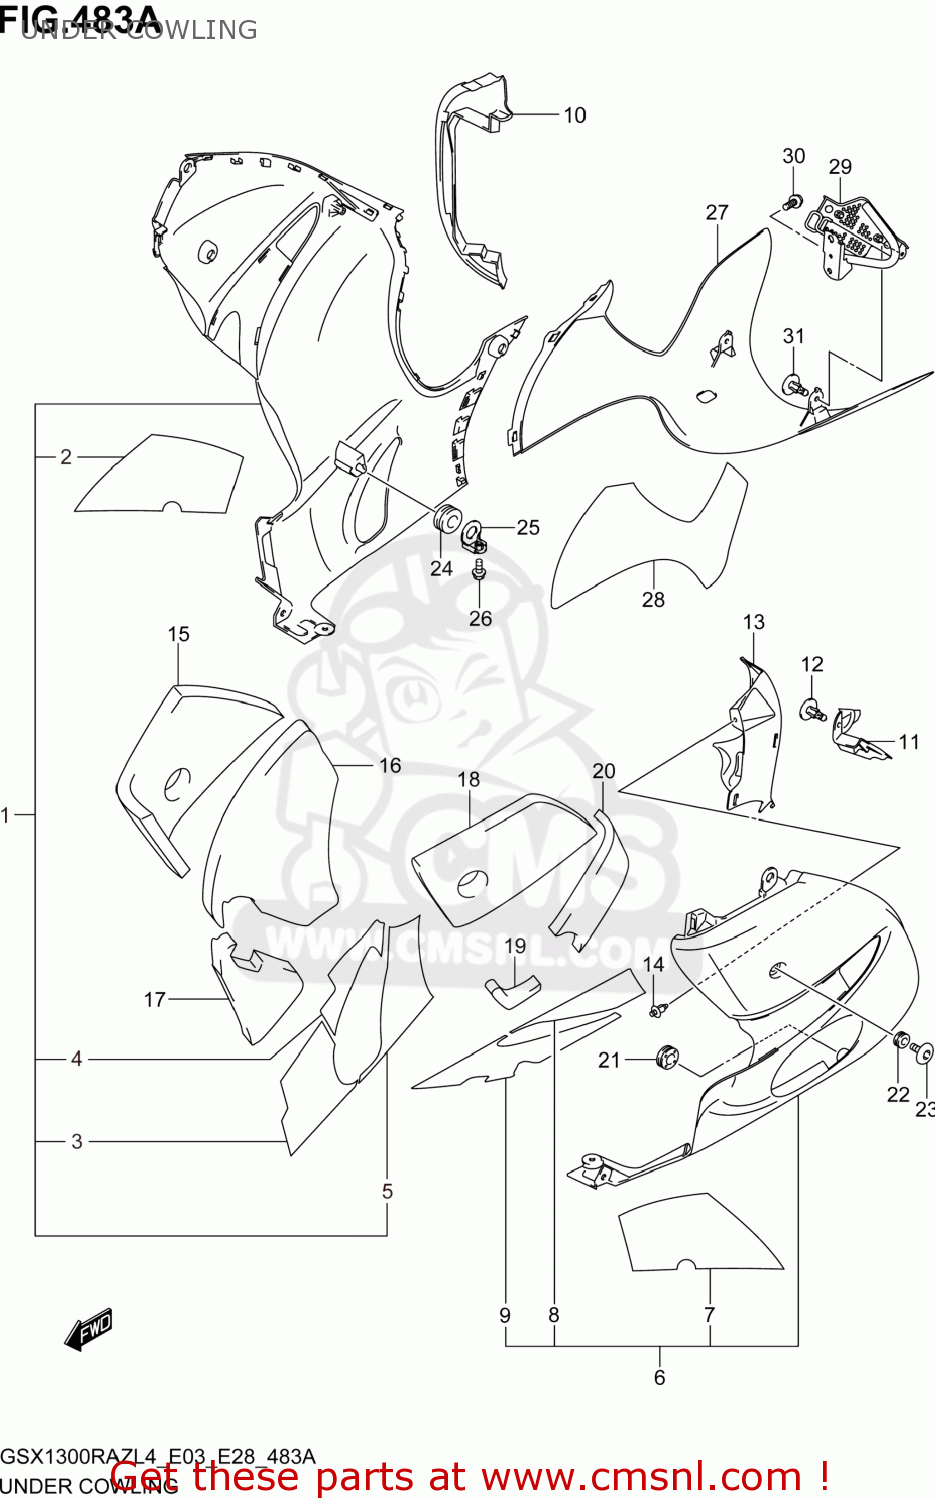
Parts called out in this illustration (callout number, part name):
1	COWLING,UNDER,R(BLACK)
2	TAPE,UNDER COWLING,R
3	SHIELD,UNDER COWL HEAT,R NO.1
4	SHIELD,UNDER COWL HEAT,R NO.3
5	SHIELD,UNDER COWL HEAT,R NO.2
6	COWLING,UNDER,L(BLACK)
7	TAPE,UNDER COWLING,L
8	SHIELD,UNDER COWL HEAT,L NO.1
9	SHIELD,UNDER COWL HEAT,L NO.2
10	PROTECTOR,COWLING UNDER,R
11	PROTECTOR,COWLING UNDER,L
12	CLIP
13	COVER,UNDER COWL,L
14	CLIP(BLACK)
15	CUSHION,UNDER COWLING,R NO.1
16	CUSHION,UNDER COWLING,R NO.2
17	CUSHION,UNDER COWLING,R NO.3
18	CUSHION,UNDER COWLING,L NO.1
19	CUSHION,UNDER COWLING,L NO.2
20	CUSHION,UNDER COWLING,L NO.3
21	CUSHION,UNDER COWLING,L
22	CUSHION
23	BOLT(6X20)
24	CUSHION
25	PLATE,UNDER COWL
26	BOLT
27	COWLING,UNDER RR
28	SHIELD,UNDER COWL HEAT
29	BRACKET,RR UNDER COWLING
30	BOLT
31	CLIP
